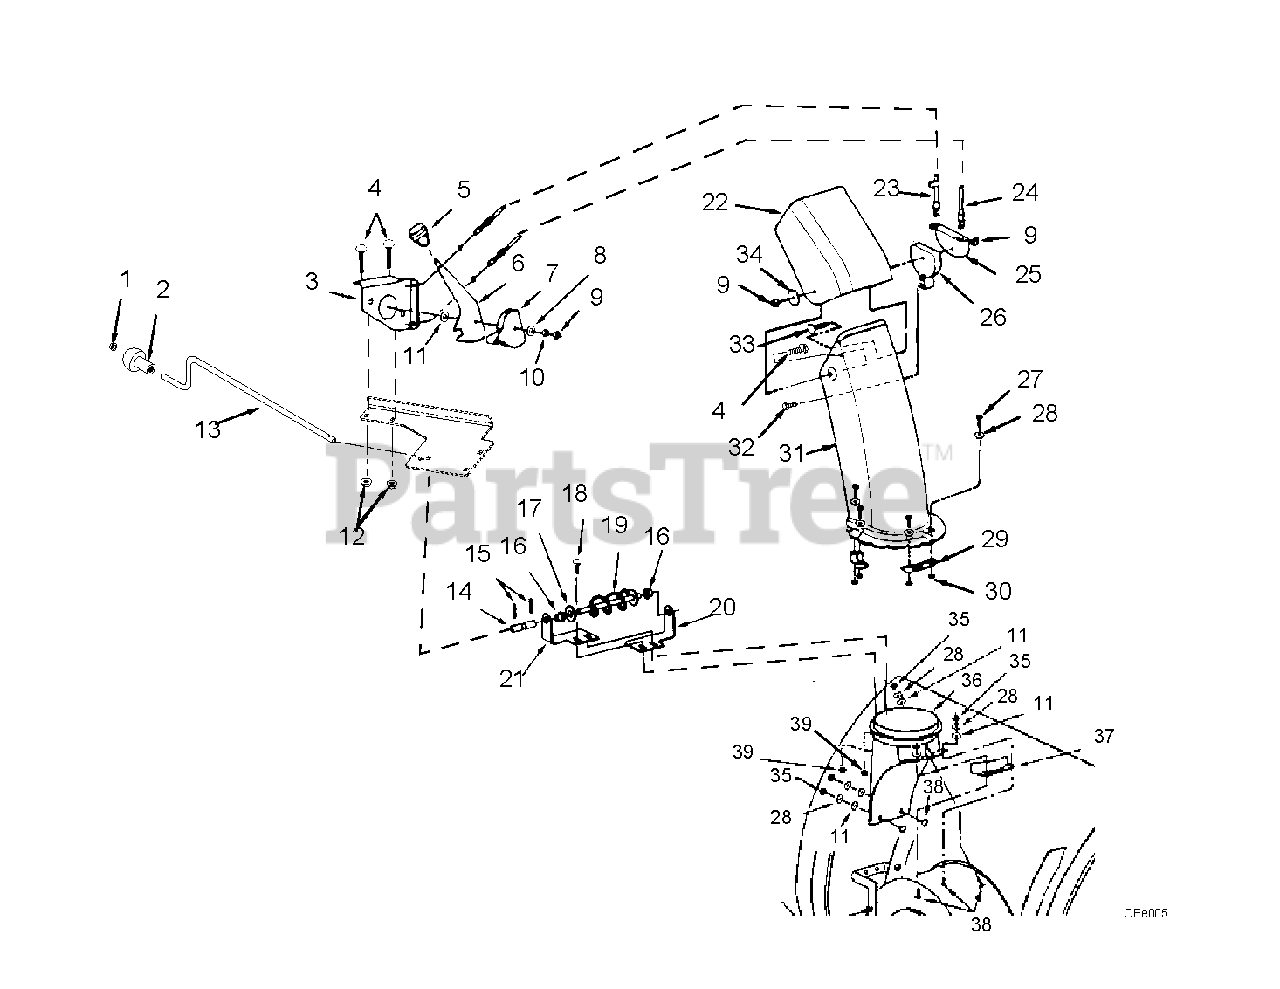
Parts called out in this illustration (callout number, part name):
1	Cap, .38 Rod
3	Assembly, Chute Tilt Bracket
4	Bolt, Round Head Square Neck .31-18 x .75 Grade 5
5	Knob
6	Handle, Chute Tilt
7	Guide, Cable
8	Washer, 5/16
9	Nut, Hex Lock 5-16-18
10	Washer, Locking .31 x .078 Regular
11	Washer, Flat Nylon .375 x .75 x .060
12	Nut, Locking Top Flange .31-18
13	Crank, Chute
15	Roll Pin, 1/8 x 5/8
16	Plastic Bushing, 3/8
17	Flat Washer, 3/8
18	Carriage Bolt, 5/16-18 x 1
19	Chute Crank Assembly
20	Chute Crank Bracket, Front
21	Chute Crank Bracket, Rear
22	Chute, Upper
23	Cable, Chute Control with Clip
24	Cable, Chute Control
25	Bracket, Cable
26	Guide, Cable
27	Hex Bolt, 1/4-20 x 1
28	Washer, 1/4
29	Chute Keeper
30	Hex Lock Nut, 1/4
31	Chute, Lower
32	Screw Machine .25-20 x .75 Hex Washer Head
33	Carriage Bolt, 5/16-18 x 1-1/2
34	Washer, 5/16
35	Hex Lock Nut 1/4-20
36	Chute Adapter
37	Chute Reinforcement
38	Carriage Bolt, 1/4-20 x 3/4
39	Nut, Locking Top Flange .31-18
